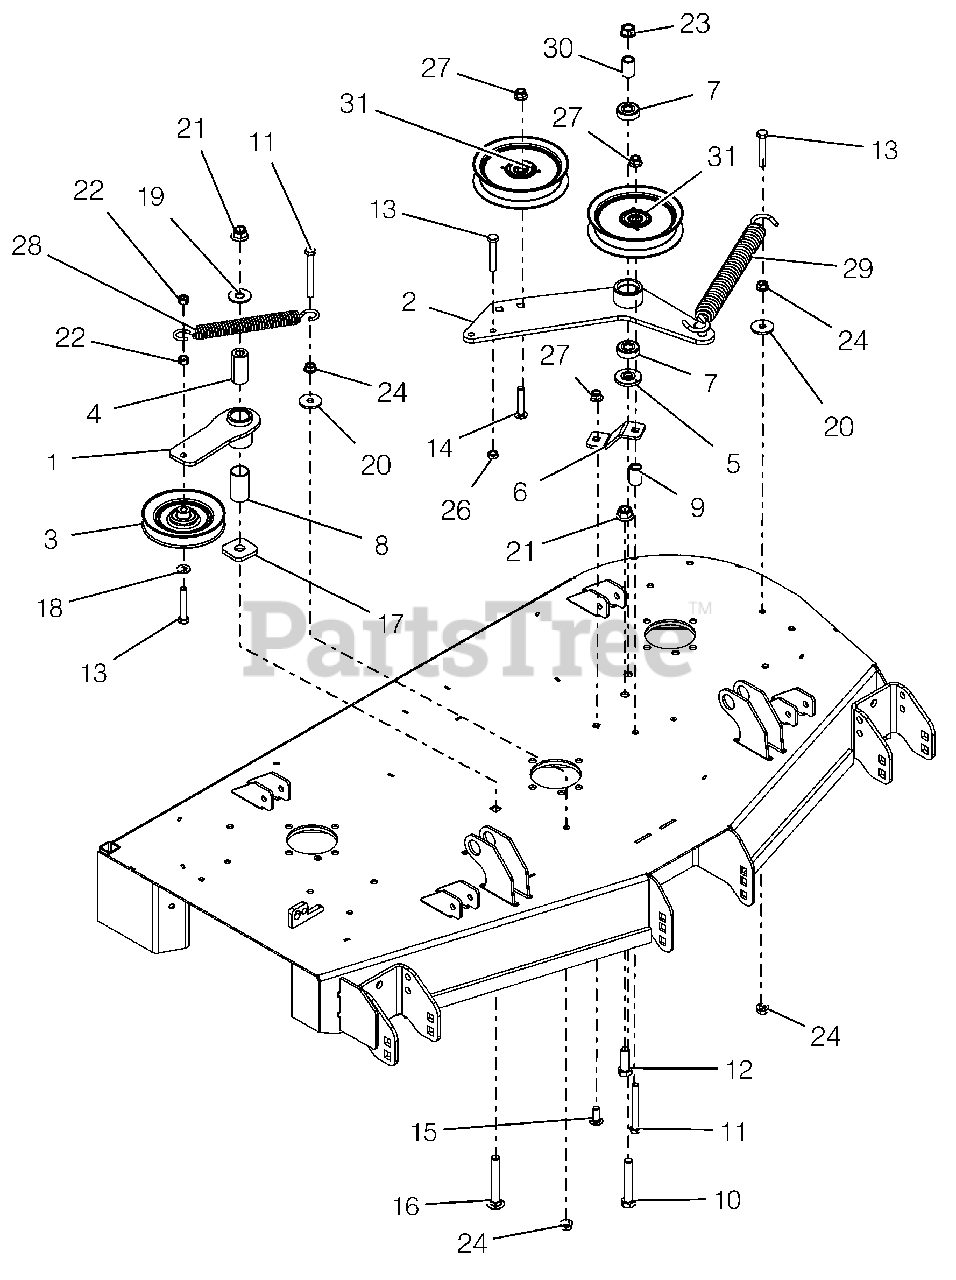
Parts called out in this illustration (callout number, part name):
1	WMT, IDLER ARM - BLACK
2	DECK PTO IDLER ARM WLDMT - BLK
3	IDLER, V-5.00"
4	BSHG, SPCR .502X.997X2.03 PM
5	SPACER, IDLER ARM
6	PTO FIXED IDLER MTG BRKT -RED
7	BRG-BALL .500X1.38X.437
8	BSHG, 1.00X1.125X1.937
9	BUSHING, SLV .380X.750X1.190
10	@BLT-HEX .50-13X3.00 GR5 YWZC
11	@BLT-HEX .38-16X3.25 GR5 YWZC
12	@BLT-HEX .50-13X1.50 GR5 YWZC
13	@BLT-HEX .38-16X2.25 GR5 YWZC
14	BLT-RDHDSQNK .38-16X2.00 SHTYW
15	@BLT-RDHDSHSQNK.38-16X1.0 G5YZ
16	@BLT-RDHDSQNK .50-13X3.50 G5YZ
17	WSHR-FLT .640X1.75X.250
18	@WSHR-FL-STL.406X.812X.065 YWZ
19	@WSHR-FL-STL.563X1.38X.109YWZC
20	WSHR-FL-STL .406X1.375X.135 YZ
21	@NUT-LK-NYL-FLG .50-13 YWZC
22	@NUT-LK-CTR .38-16 YWZC
23	NUT-LK-CTR-FLG .50-13 YWZC
24	@NUT-SPNLK-FLG .375-16 YWZC
26	NUT-HEX-JAM .375-16 YWZC
27	@NUT-LK-NYL-FLG .38-16 YWZC
28	SPRING, EXTENSION
29	SPRING, EXTENSION
30	SPACER .510 X .75 X 1.1485
31	IDLER, FLAT 5.00"
